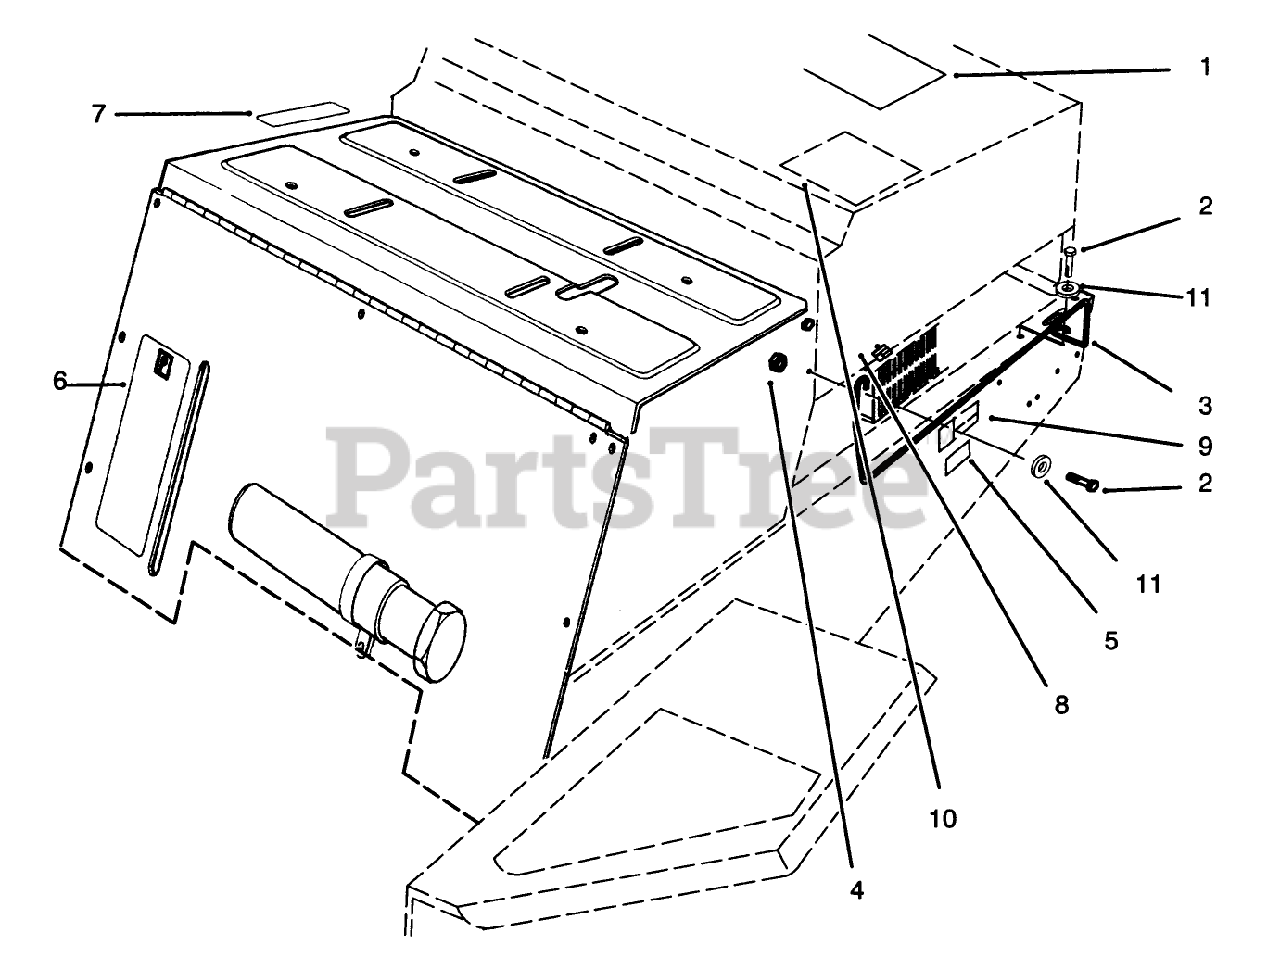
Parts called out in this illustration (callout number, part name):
1	DECAL-REFUELING
2	SCREW-HH
3	Guard-Muffler
4	NUT-LOCK, NI
5	DECAL-WARNING
6	DECAL - PARKING BRAKE
7	DECAL - LIFT CONTROL
8	DECAL-SURFACE, HOT
9	DECAL-SURFACE, HOT
10	DECAL-BLANK
11	WASHER-PLAIN
